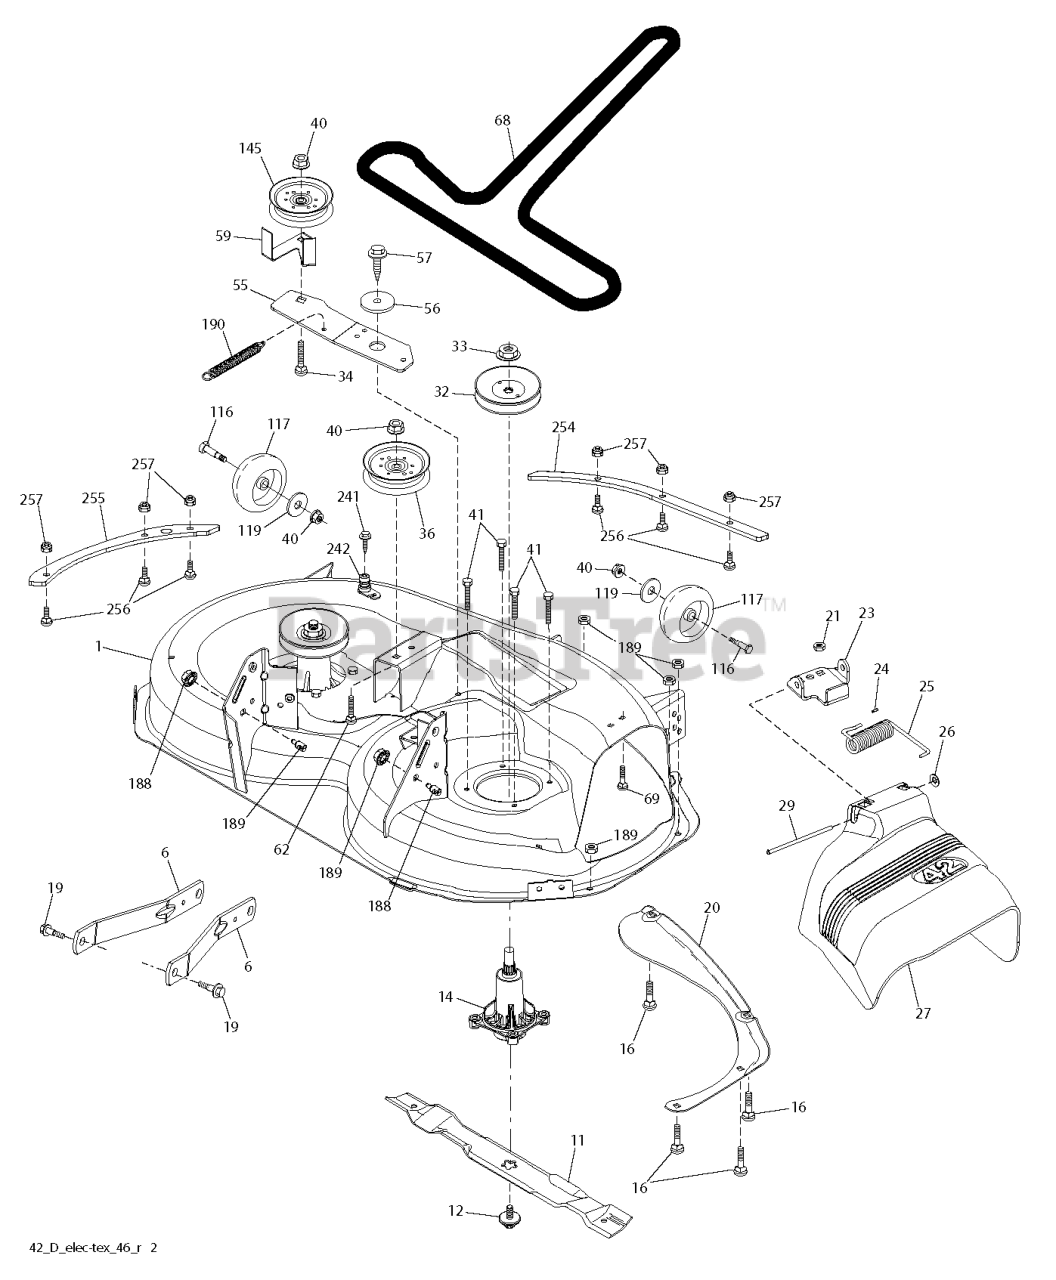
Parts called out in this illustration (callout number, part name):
1	Decks
6	ARM.SUSPENSION.MOWER.R
11	42" HI-LIFT BLADE
12	SCREW.SEMS.7/16-20X1.HEX.HEAD
14	KIT.MANDREL.NONGREASE.TALL
16	BOLT ROUND HEAD SQUARE NECK BO
19	BOLT.SHOULDER
20	BAFFLE DECK 42 SD BLACK
23	BRKT.DEFLECTOR.38"2005+
24	CAP-SLEEVE LT
25	SPRING.TORSION.DEFLECT
26	NUT PUSH M
27	SHIELD.DEFLECTOR.MOWER.42"BLAC
32	PULLEY/MANDREL
34	GSPW Bolts
36	PULLEY.IDLER.2006
40	NUT LOCK FLG 3/8-16 UNC
41	BOLT.HEX.WASHR.HED.313-18X1.19
55	IDLER.ARM.42"
56	SPACER.RETAINER
57	SCREW 3/8-16X1
59	GUARD, BELT
68	BELT V SECONDARY
117	WHEEL.GAUGE.RALLY.NARROW
145	PULLEY.IDLER.48"PRIMARY
188	STUD.W/"D"ANTI-ROTATION
190	SPRING.MOWER.DRIVE.ELECTRIC
241	SCREW.TT.#10-32X.5.3/8.FLANGE
242	PORT.WASHOUT
254	PLATES.RENFRC.42DECK.PT431FRNT
255	PLATES.RENFRCE.42DECK.X431SIDE
256	BOLT CUP HEAD SQUARE NECK 1/4-
257	NUT T
